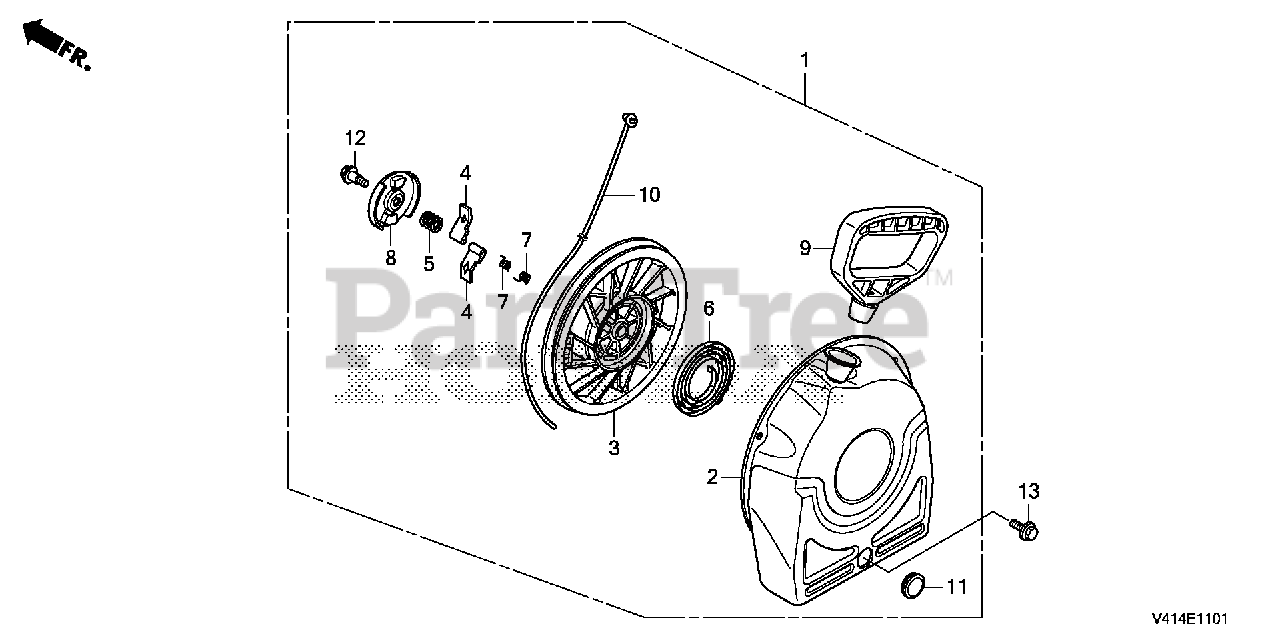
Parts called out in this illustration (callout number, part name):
1	STARTER ASSY., RECOIL (FRAME NO.)
2	CASE, RECOIL STARTER (FRAME NO.)
2	CASE, RECOIL STARTER
3	PULLEY, RECOIL STARTER (FRAME NO.)
3	PULLEY, RECOIL STARTER
4	RATCHET (FRAME NO.)
4	RATCHET
5	SPRING, FRICTION (FRAME NO.)
5	SPRING, FRICTION
6	SPRING, STARTER RETURN (FRAME NO.)
6	SPRING, STARTER RETURN
7	SPRING, RATCHET (FRAME NO.)
7	SPRING, RATCHET
8	RETAINER, SPRING (FRAME NO.)
8	RETAINER, SPRING
9	GRIP, STARTER (FRAME NO.)
9	GRIP, STARTER
10	ROPE, RECOIL STARTER
10	ROPE, RECOIL STARTER (FRAME NO.)
11	GROMMET (FRAME NO.)
11	GROMMET
12	SCREW, CENTER (FRAME NO.)
12	SCREW, CENTER
13	BOLT, FLANGE (6X10)
